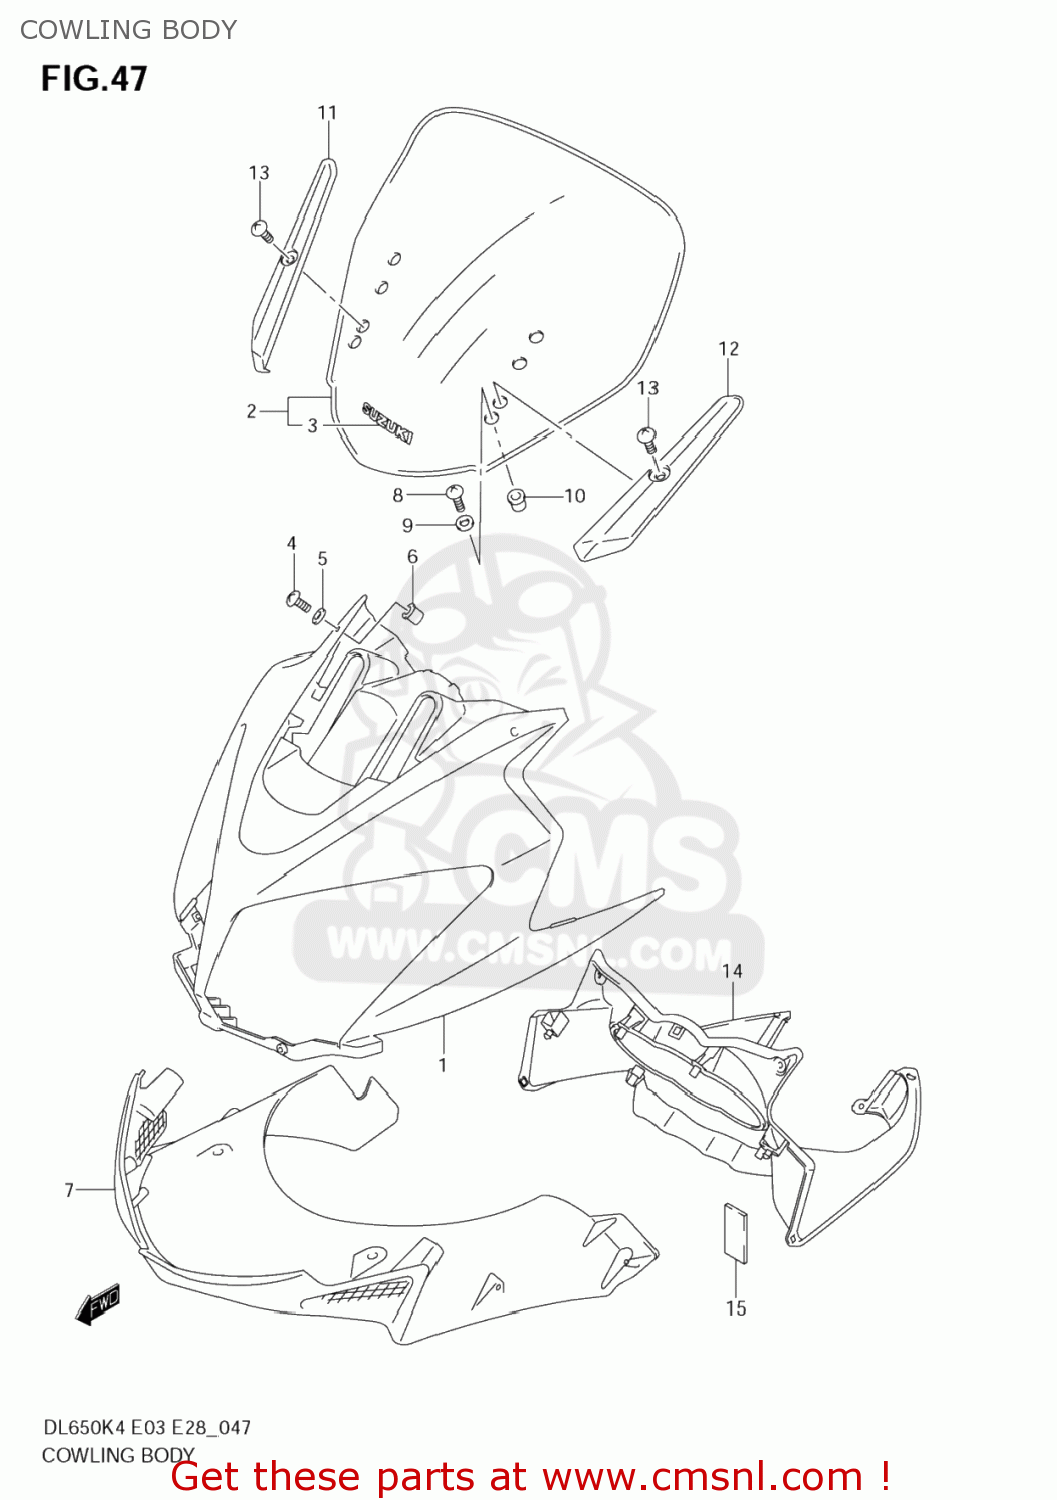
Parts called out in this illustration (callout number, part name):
1	COWLING COMP,B
2	WINDSCREEN
3	TAPE,WINDSCREEN
4	SCREW(5X22)
5	WASHER
6	NUT,UNDER COWL BRACE RR
7	COVER,COWLING INNER
8	SCREW 5X20
9	WASHER(5.2X14X1.5)
10	NUT
11	COVER,WINDSCRE
12	COVER,WINDSCRE
13	SCREW(5X16)
14	PANEL,METER(BLACK)
15	CUSHION
